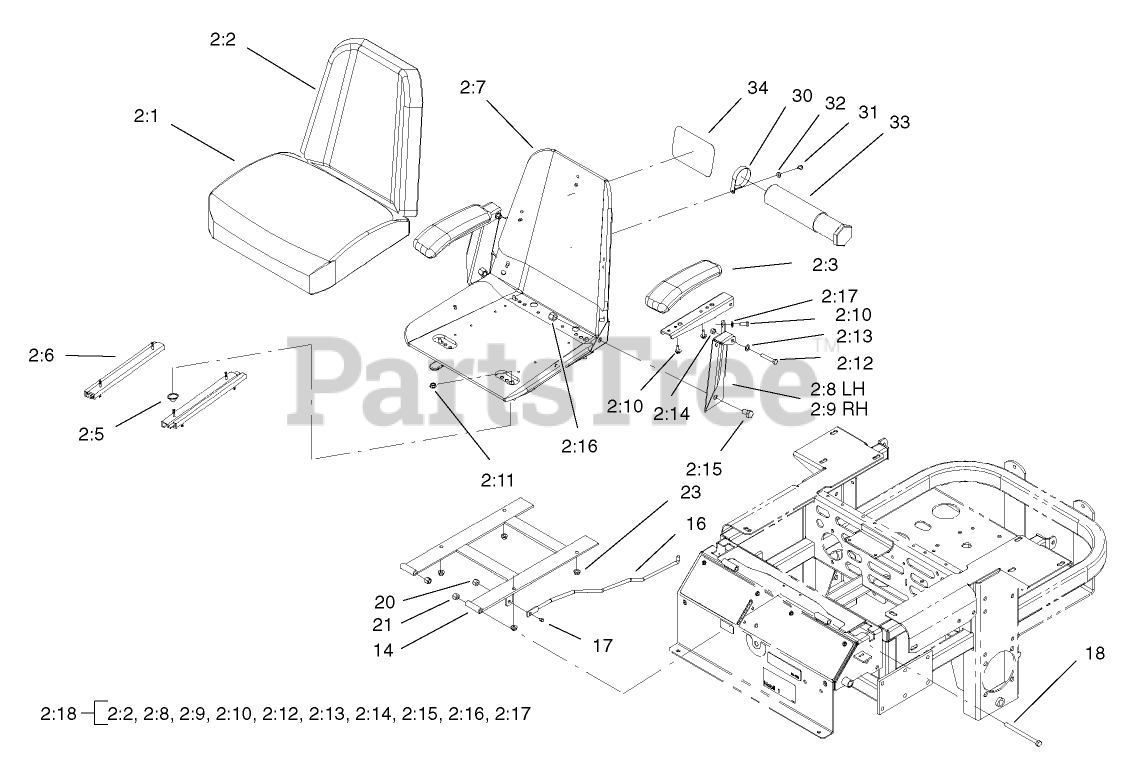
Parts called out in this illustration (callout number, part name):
2	SEAT ASM
2:1	CUSHION-SEAT, BOTTOM
2:2	CUSHION-SEAT, BACK
2:3	CUSHION-ARMREST
2:5	SPACER-TRACK
2:6	TRACK-SEAT
2:7	FRAME-SEAT
2:8	Bracket-Armrest, LH
2:9	Bracket-Armrest, RH
2:10	SCREW-HH
2:11	NUT-HF
2:12	SCREW-HH
2:13	WASHER-PLAIN
2:14	NUT-LOCK, NI
2:15	SCREW-HH
2:16	NUT-LOCK, NI
2:17	WASHER-FLAT
2:18	ARMREST KIT
14	FRAME-SEAT
16	ROD-HOLDUP, SEAT
17	SCREW-HH
18	SCREW-HH
20	NUT-LOCK, NI
21	NUT-LOCK, NI
23	NUT-HF
30	CLAMP-R
31	SCREW-HWHTF
32	WASHER-FLAT
33	TUBE-MANUAL
34	DECAL
